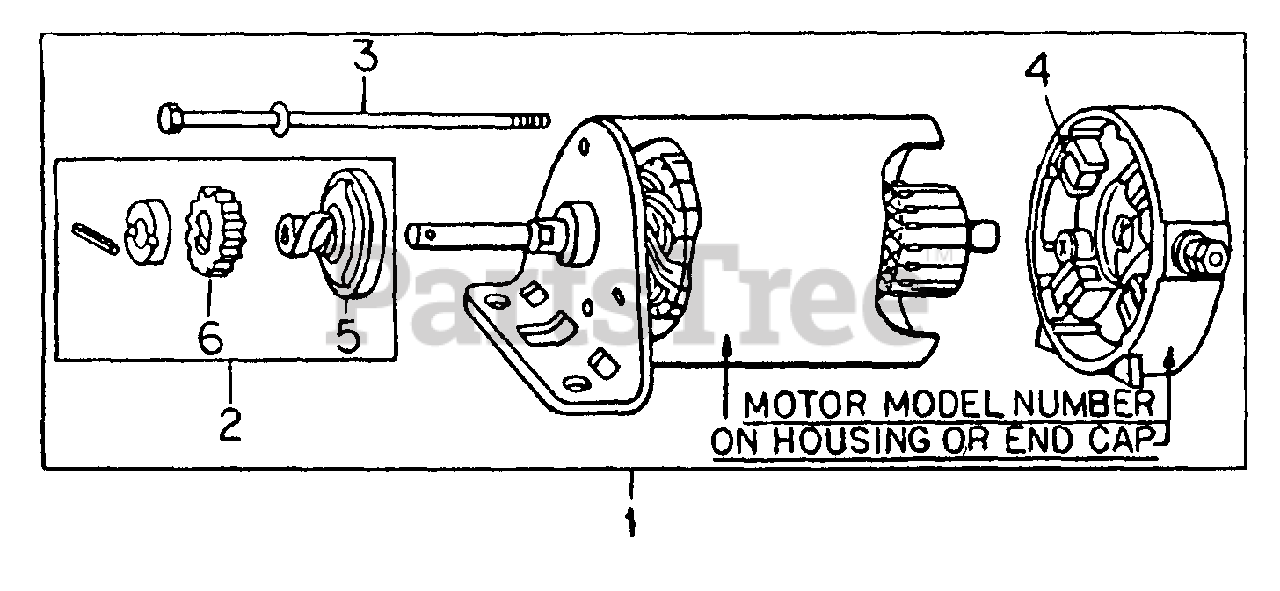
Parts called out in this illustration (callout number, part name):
1	MOTOR ASSY, STARTER
2	DRIVE
3	BOLT, 1/4-20 X 4 ZND HEX-HD MACH
4	BRUSH KIT
5	CLUTCH ASSY, STARTER
6	GEAR, STARTER DRIVE
